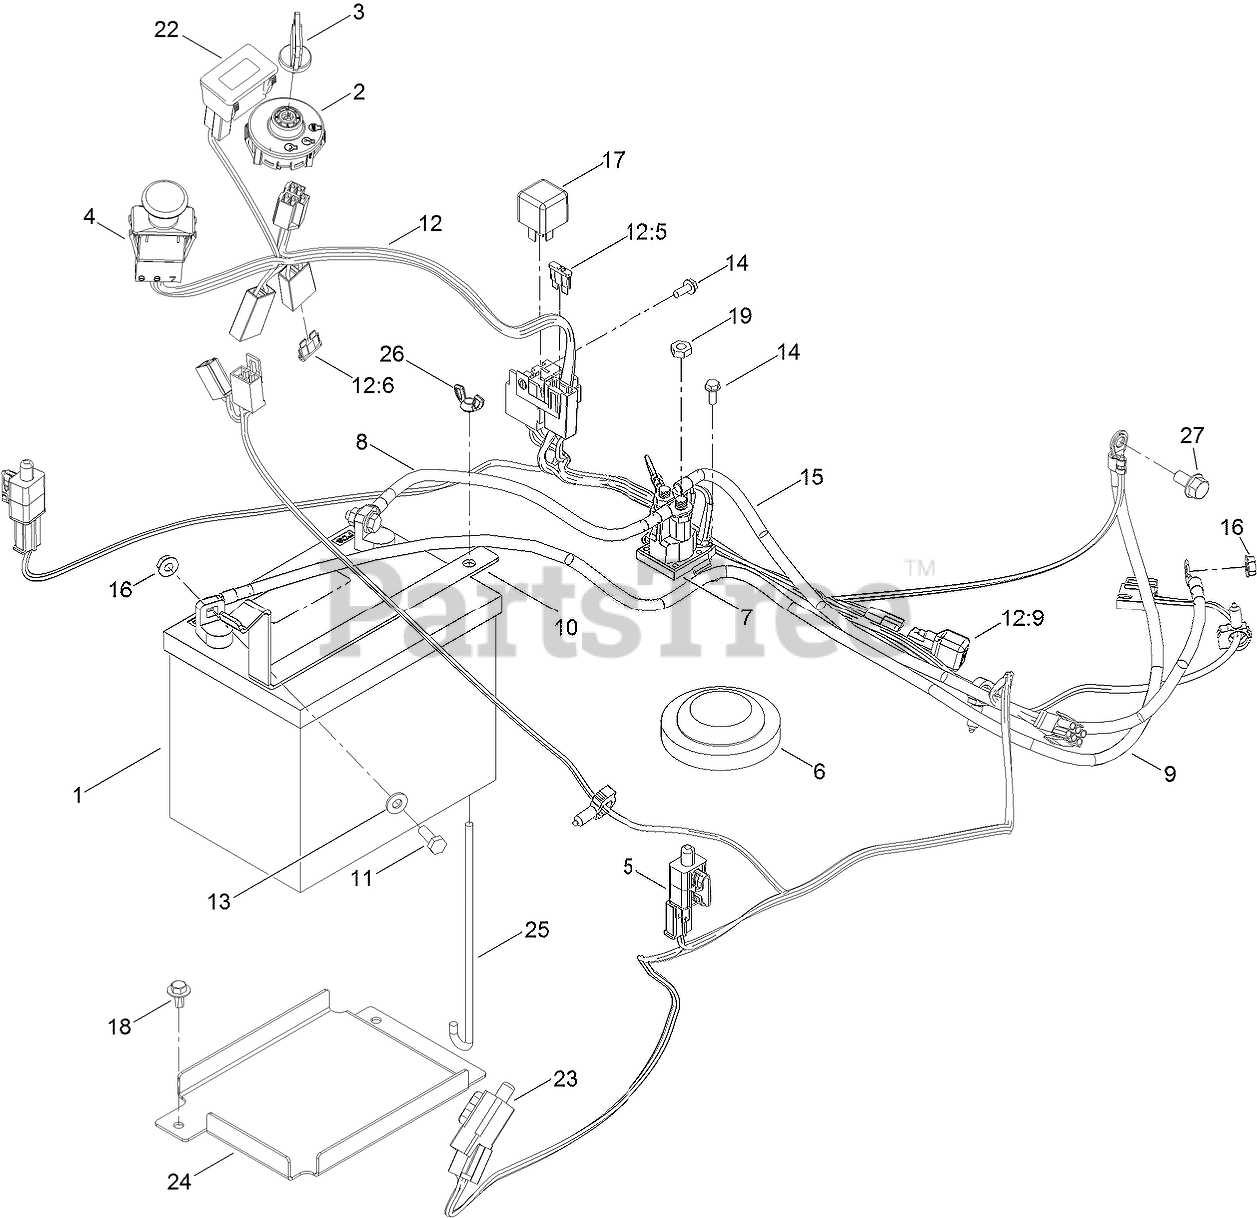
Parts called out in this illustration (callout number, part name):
1	BATTERY
2	SWITCH-IGNITION
3	KEY-IGNITION
4	SWITCH-PTO
5	SWITCH
6	SWITCH-SEAT
7	SOLENOID
8	CABLE-BATTERY, POSITIVE
9	CABLE-BATTERY, NEGATIVE
10	STRAP-BATTERY
11	SCREW-HH
12	HARNESS-WIRE
12:5	FUSE-BLADE, 30 AMP
12:6	FUSE-BLADE, 25 AMP
13	WASHER-FLAT
14	SCREW-TAPTITE
15	WIRE-21 INCH
16	NUT-HF
17	RELAY
18	SCREW-HHFTF
19	NUT-JAM
22	HOURMETER
23	SWITCH-REVERSE
24	TRAY-BATTERY
25	BOLT-HOLDDOWN
26	WINGNUT
27	SCREW-HHF
